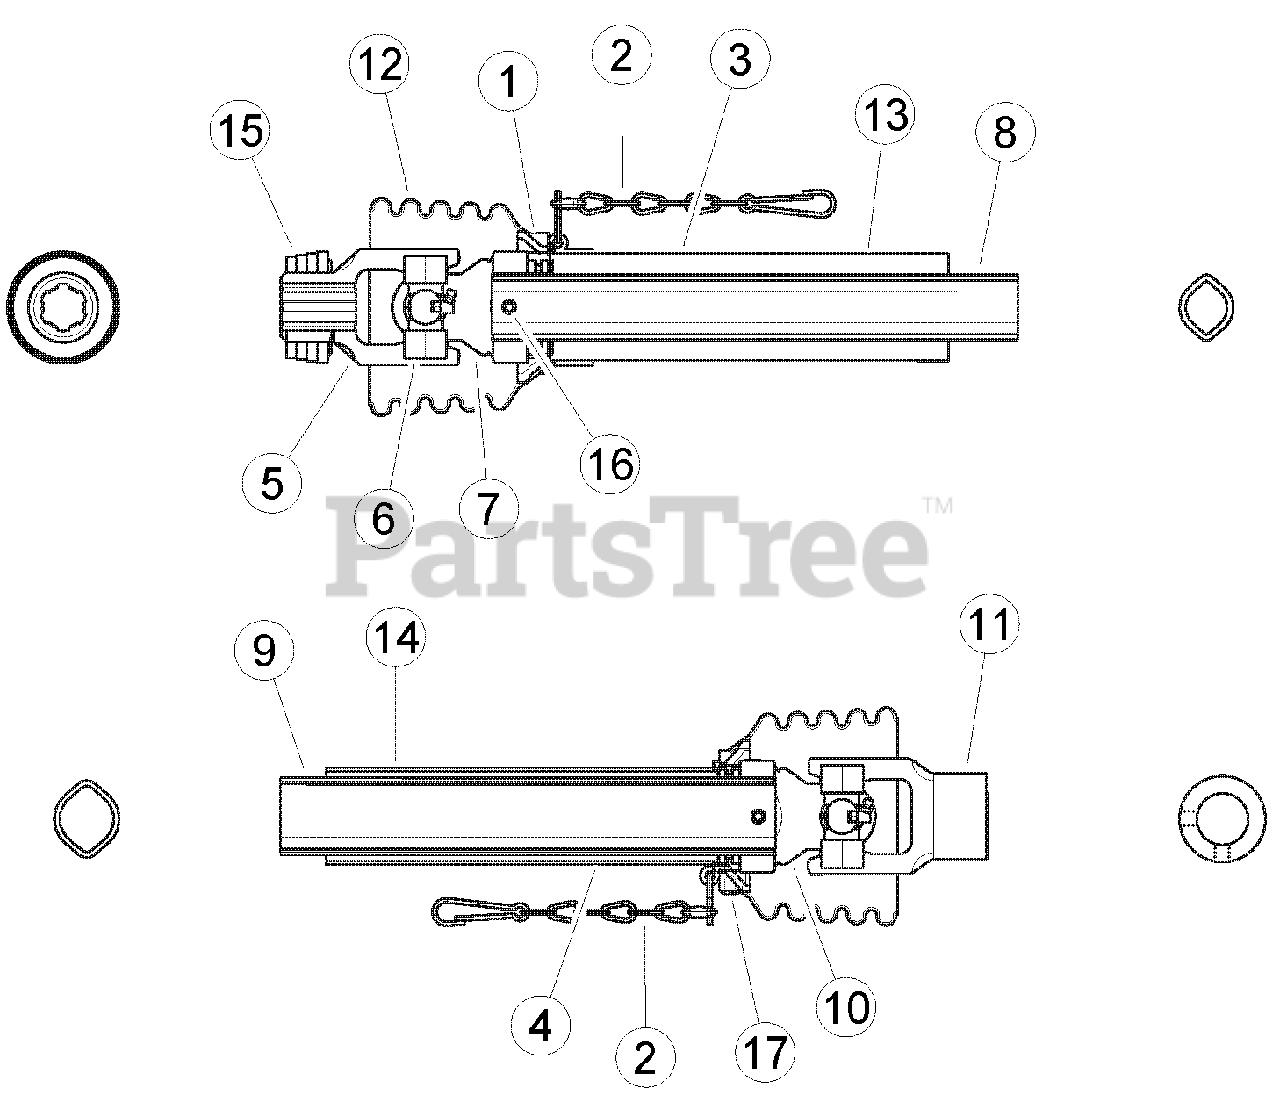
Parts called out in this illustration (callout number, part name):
1	BEARING, RING SC15
2	SAFETY CHAIN
3	DECAL, OUT
4	DECAL, IN
5	YOKE, 3/8 - 6 SPL. ASGE
6	CROSS & BEARING KIT
7	YOKE, INBOARD OV
8	INNER PROFILE OV
9	OUTER PROFILE I
10	YOKE, INBOARD I
12	SHIELD, CONE 4 RIB
13	SHIELD, OUTER TUBE OVL.
14	SHIELD, INNER TUBE RND
15	KIT, RETAINING RING / TRACTOR SIDE
16	PIN, SPRING 10 X 65
